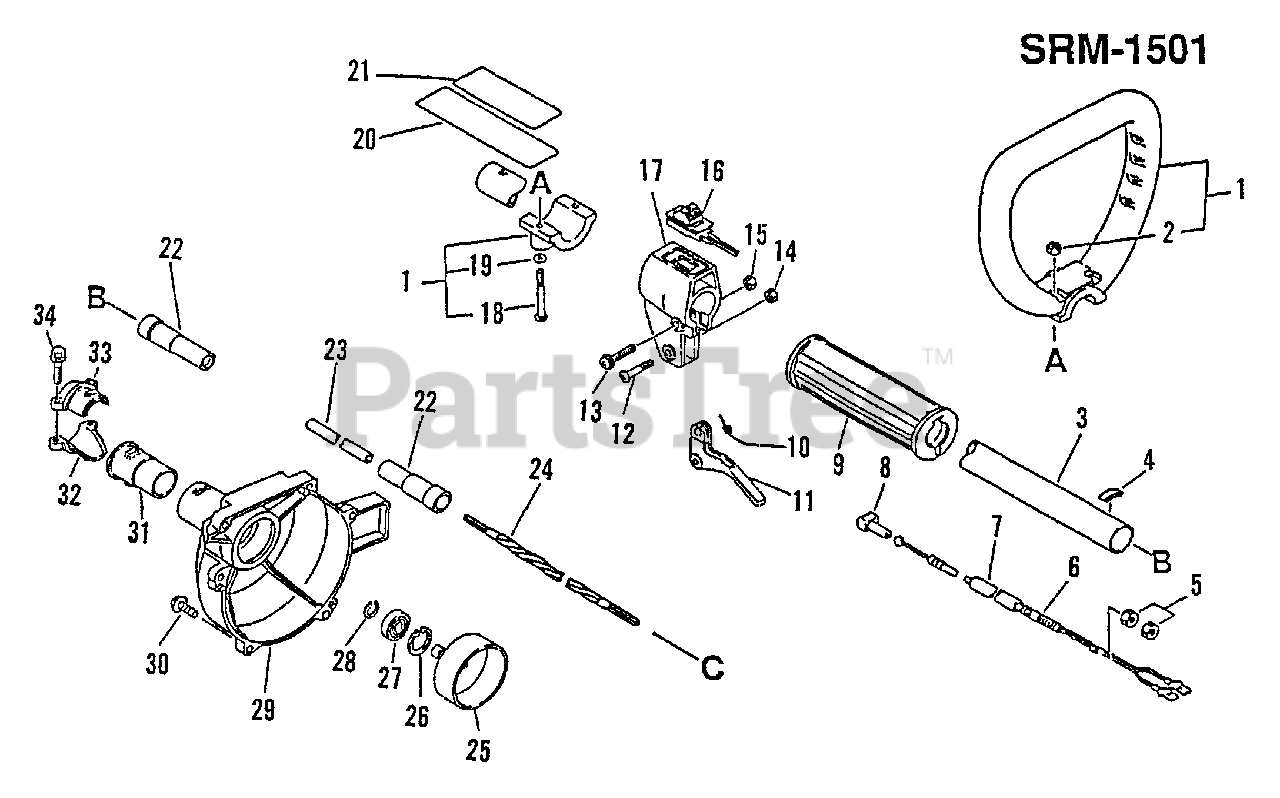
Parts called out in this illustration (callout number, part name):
1	LOOP HANDLE ASSY
2	NUT M5
3	MAIN PIPE ASSY 25×1500
4	LABEL - ALIGNMENT
6	CABLE, THROTTLE
8	GUIDE, CABLE
9	GRIP
10	SPRING, THROTTLE
11	TRIGGER, THROTTLE
13	SCREW 5×30
14	NUT, LOCK M5
15	NUT M5
16	IGNITION SWITCH ASSY
17	BRACKET, THROTTLE CONTROL
18	SCREW 5×40
19	WASHER, FLAT 5.5×10×0.8
20	LABEL - CAUTION
21	LABEL - CAUTION
23	LINER - FLEXIBLE
24	DRIVESHAFT - FLEXIBLE L= 1522
25	DRUM, CLUTCH
26	RING, SNAP 28
27	BEARING, BALL 6201-ZZ
28	RING, RETAINING - 12
29	COVER, FAN
30	SCREW 4×16
33	HOLDER, MAIN PIPE - UPPER
34	BOLT - 5×25
